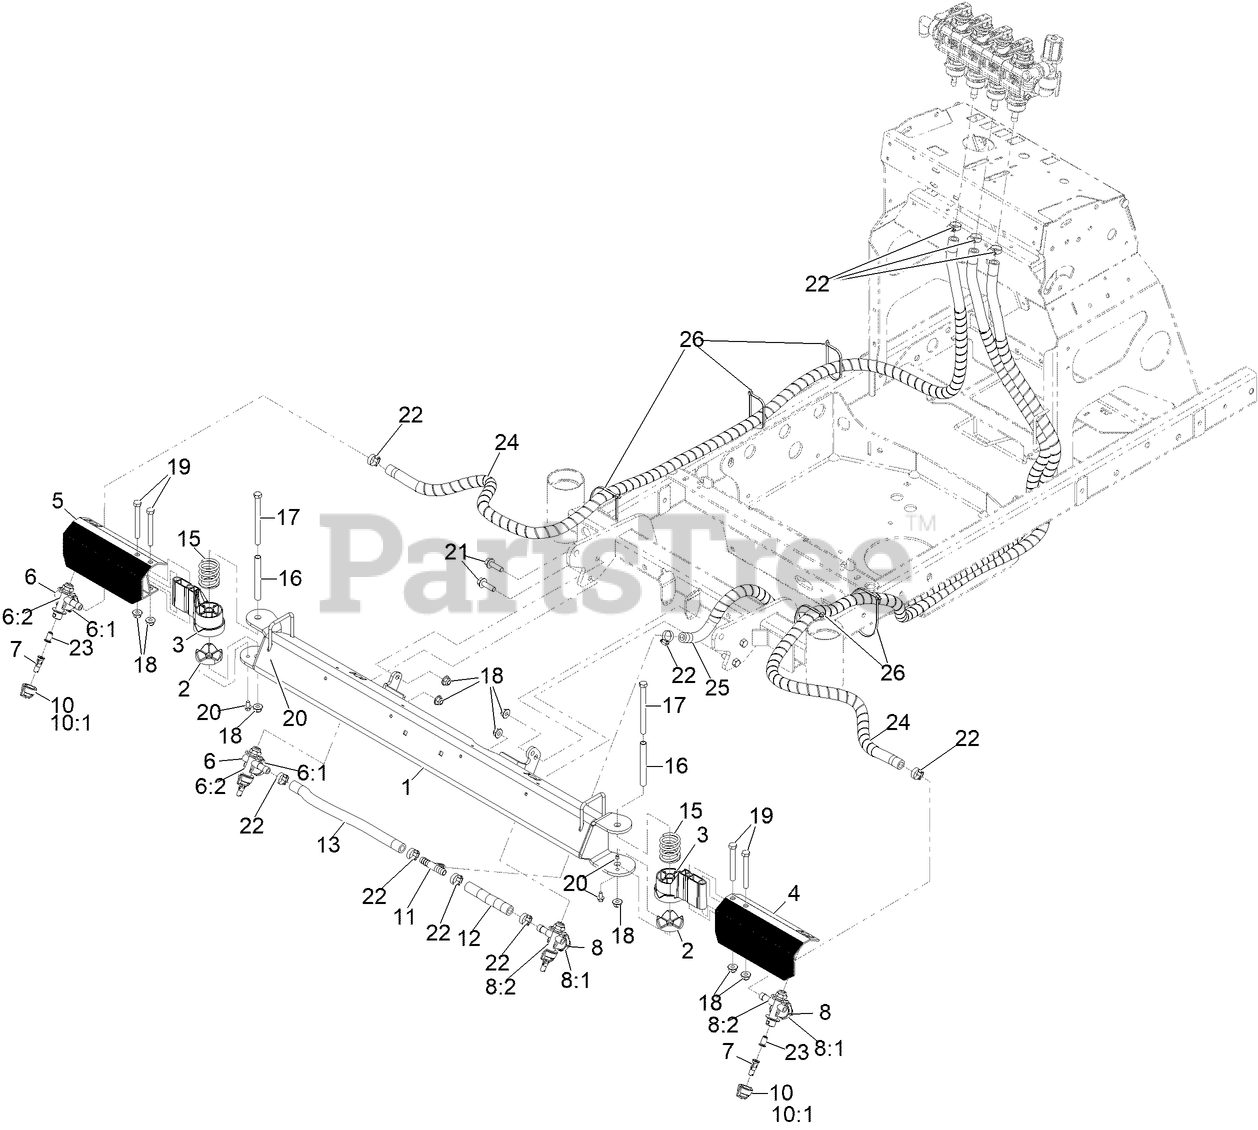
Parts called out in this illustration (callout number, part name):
1	BOOM-CENTER, WELD
2	BOOM-PIVOT
3	HINGE-BOOM
4	BOOM-WING, LH
5	BOOM-WING, RH
6	BODY-NOZZLE, RIGHT
6:1	CAP-SPRAYER NOZZLE
6:2	DIAPHRAGM-SPRAYER NOZZLE
7	TIP-SPRAY, 025
8	BODY-NOZZLE, LEFT
8:1	CAP-DIAPHRAM
8:2	DIAPHRAGM FOR CHECK VALVE
10	CAP-NOZZLE
10:1	SEAT-GASKET
11	FITTING-TEE
12	Hose-Spray
13	Hose-Spray
15	SPRING-COMPRESSION
16	SPACER-BOOM, PIVOT
17	SCREW-HH
18	Nut-Hex Flange
19	SCREW-HH
20	SCREW-HWH
21	SCREW-HHF
22	CLAMP-HOSE
23	STRAINER-NOZZLE, 50M 5PSI
24	HOSE-SPRAY, WRAPPED
25	HOSE-SPRAY, WRAPPED
26	TIE-CABLE
